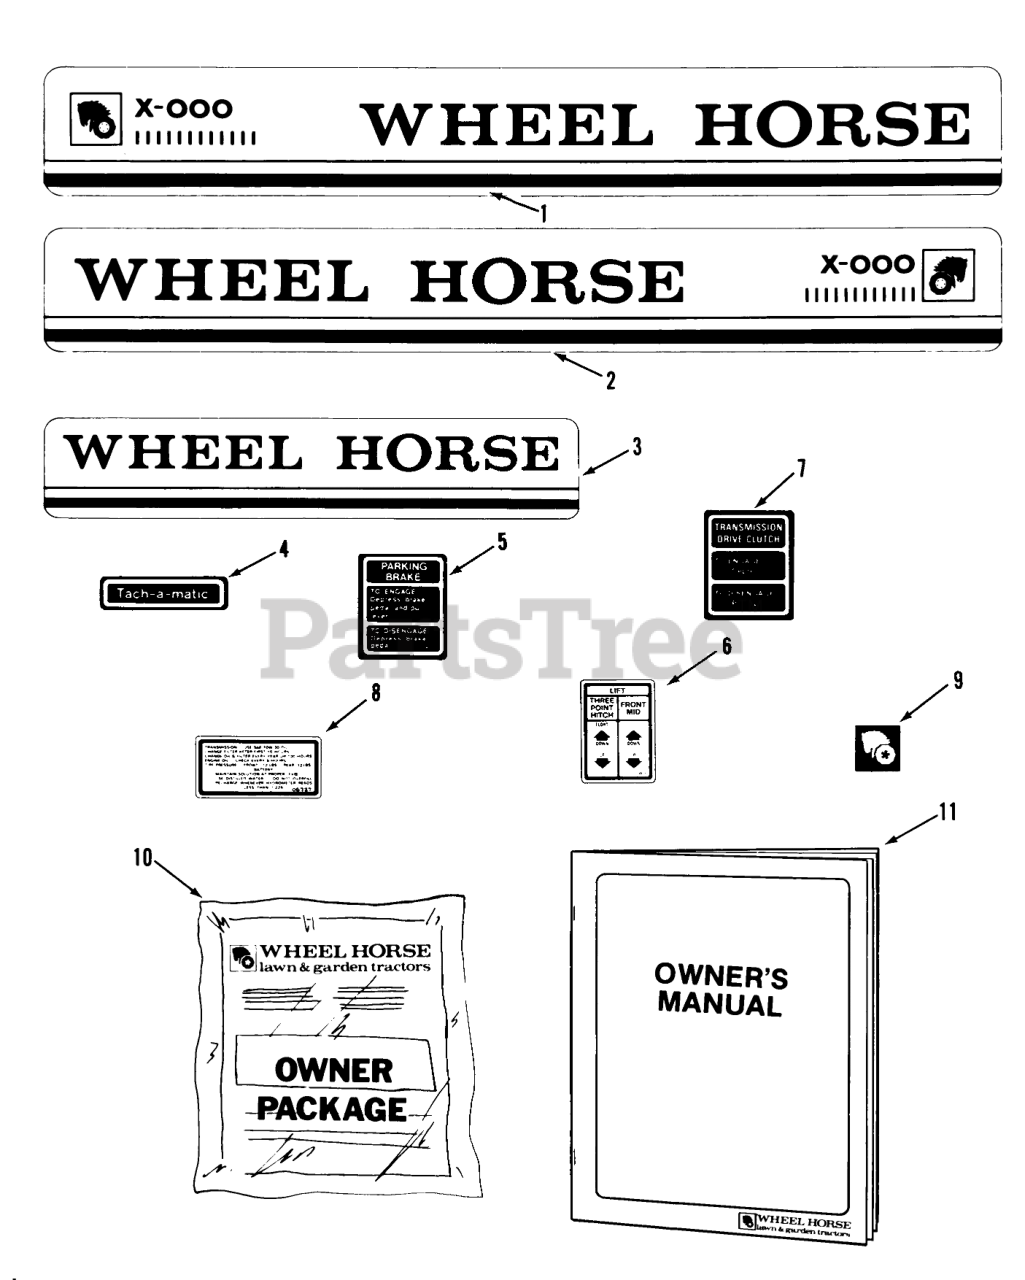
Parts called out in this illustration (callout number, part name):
1	Decal LH C-195 Twin Automatic
2	Decal RH C-195 Twin Automatic
3	DECAL-REAR
4	DECAL-TACHAMATIC
5	DECAL-PARKING BRAKE
6	DECAL LIFT
7	Decal-Transmission Clutch
8	Decal-Maintenance
9	DECAL-LOGO
10	Loose Parts Package 01-19KE01 Only
10	Loose Parts Package 01-19KE02 Only
11	Tractor Owner-s Manual 01-19KE01 Only
11	Owner-s Manual-Tractor
